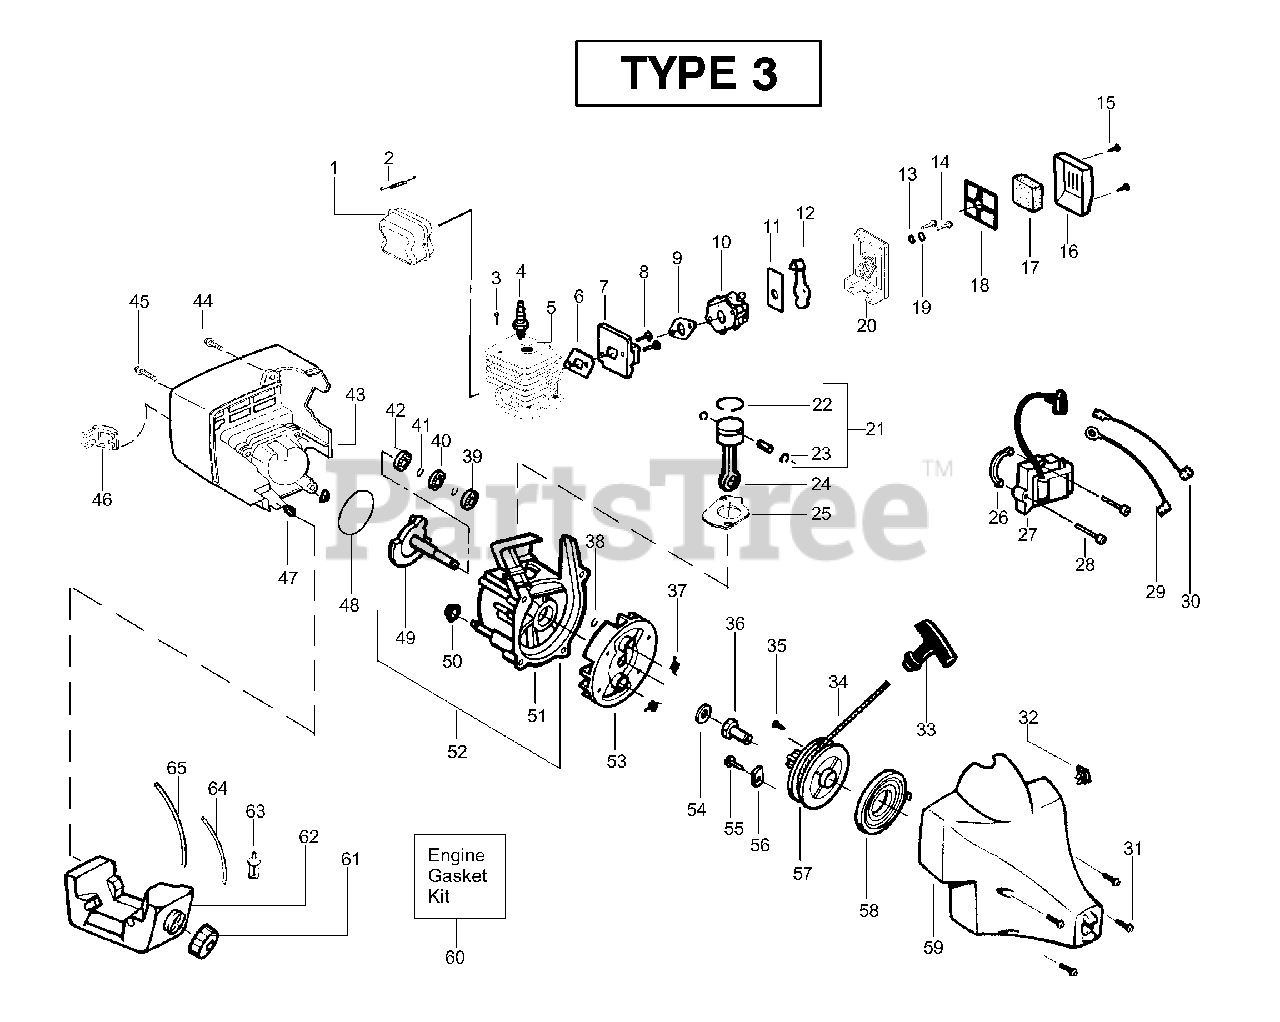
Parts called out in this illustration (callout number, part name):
1	Kit - Muffler
2	Muffler Spring
3	Screw-Cylinder
4	Spark Plug (RCJ 6Y)
5	Kit - Cylinder
6	Gasket-Cyl/Carb.(kit)
7	Adaptor-carb.
9	Gasket-Carb.(kit)
10	Kit - Carburetor Ass'y
11	Plate-Choke Mounting
12	Lever-Choke
16	Cover-Air Box
17	Foam-Air Filter
18	Plate-Air Filter Support
19	Spacer-Choke
21	Kit - Piston
22	Piston Ring
23	Retainer-Piston Pin
24	Assy-Connecting Rod
25	Gasket-Cylinder(kit)
26	Spacer-Module
27	Ignition Module
29	Assy-Ground Wire
30	Assy-Leadwire
31	Screw
32	Kit-Momentary Switch
33	Handle-Starter
34	Kit - Rope
36	Coupling-Drive
37	Spring-Starter Dog
38	Retain. Ring-C'shaft
39	Bearing-Outer
40	Seal-C'case
41	Retainer Ring-C'case
42	Bearing-Inner
45	Screw
46	Guard-Muffler
47	Isolator-Shroud
48	O-Ring-C'case(kit)
49	Assy-Crankshaft
50	Isolator-Crankcase
51	Assy-Crankcase
52	Assy-C'case & C'shaft
53	Assy-Flywheel
54	Washer-Flat
56	Retainer-Can
57	Kit-Starter Pulley
58	Spring-Starter
59	Assy-Fan Housing
60	Kit-Engine Gasket
61	Assy-Fuel Cap
62	Assy-Fuel Tank
63	Assy-Fuel Pickup
64	Kit-Fuel Line
65	Kit-Fuel Line
